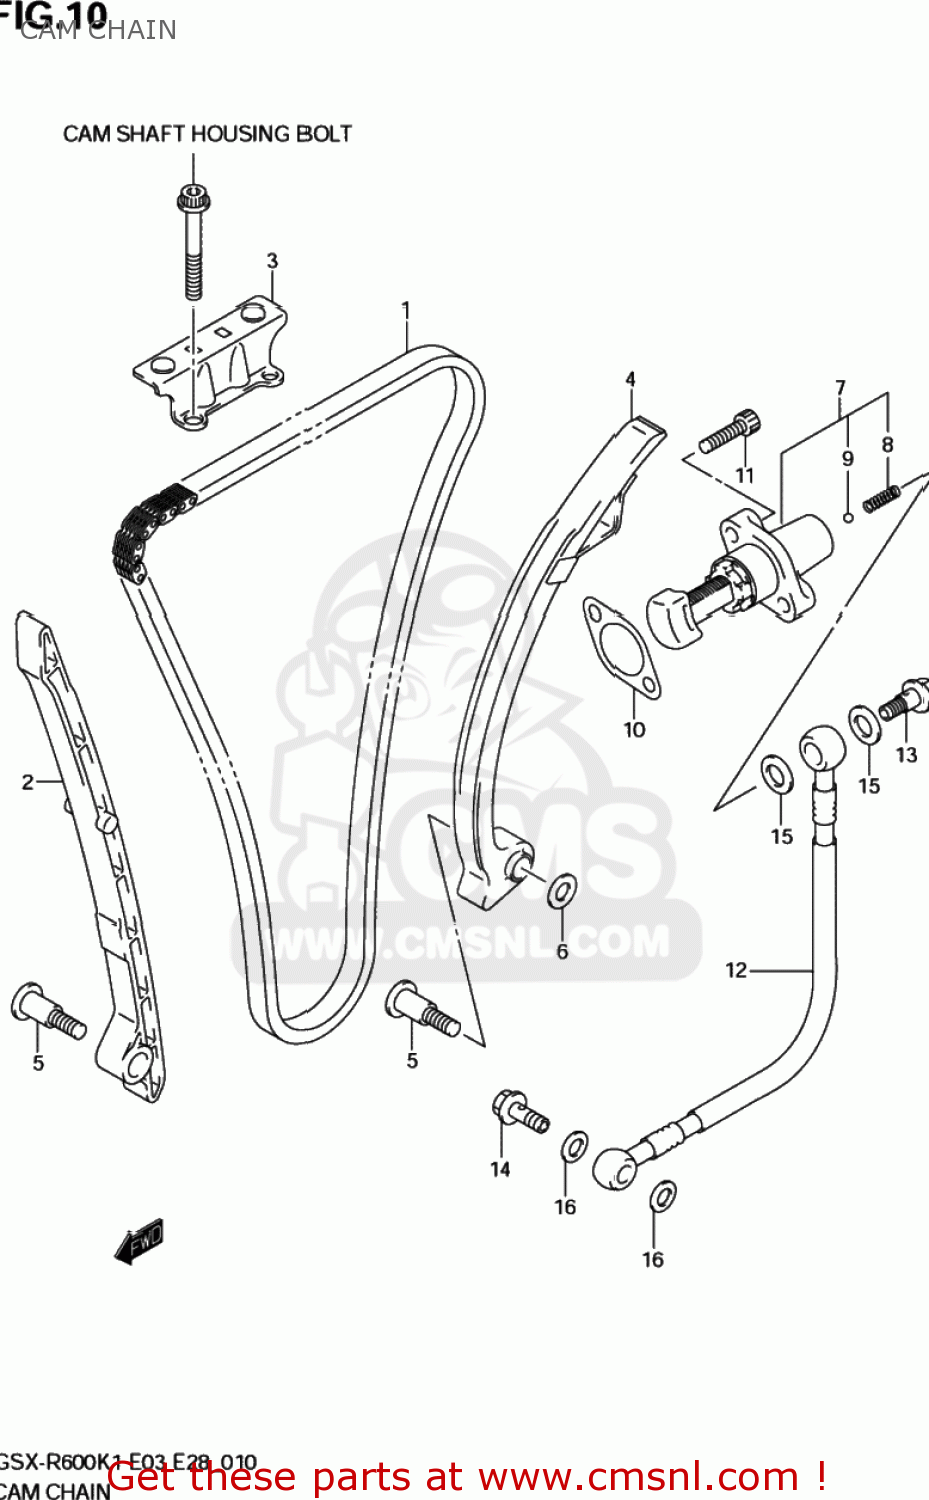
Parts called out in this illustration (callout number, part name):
1	CHAIN,CAMSHAFT DRIVE
2	GUIDE,CAM CHAIN NO.1
3	GUIDE CAM CHAIN NO,2
4	TENSIONER,CAM CHAIN
5	BOLT,CAM CHAIN TENSIONER/GUIDE
6	WASHER
7	ADJUSTER ASSY,TENSIONER
8	SPRING
9	BALL
10	GASKET,TENSIONER ADJUSTER (NAS)
11	BOLT,CL.COVER
12	HOSE,TENSIONER ADJUSTER OIL
13	BOLT,ADJ OIL HOSE UNION NO,1
14	BOLT,ADJUST OIL HOSE UNION
15	GASKET(12X17X1) (NAS)
16	GASKET 8.2X14X1 (NAS)
